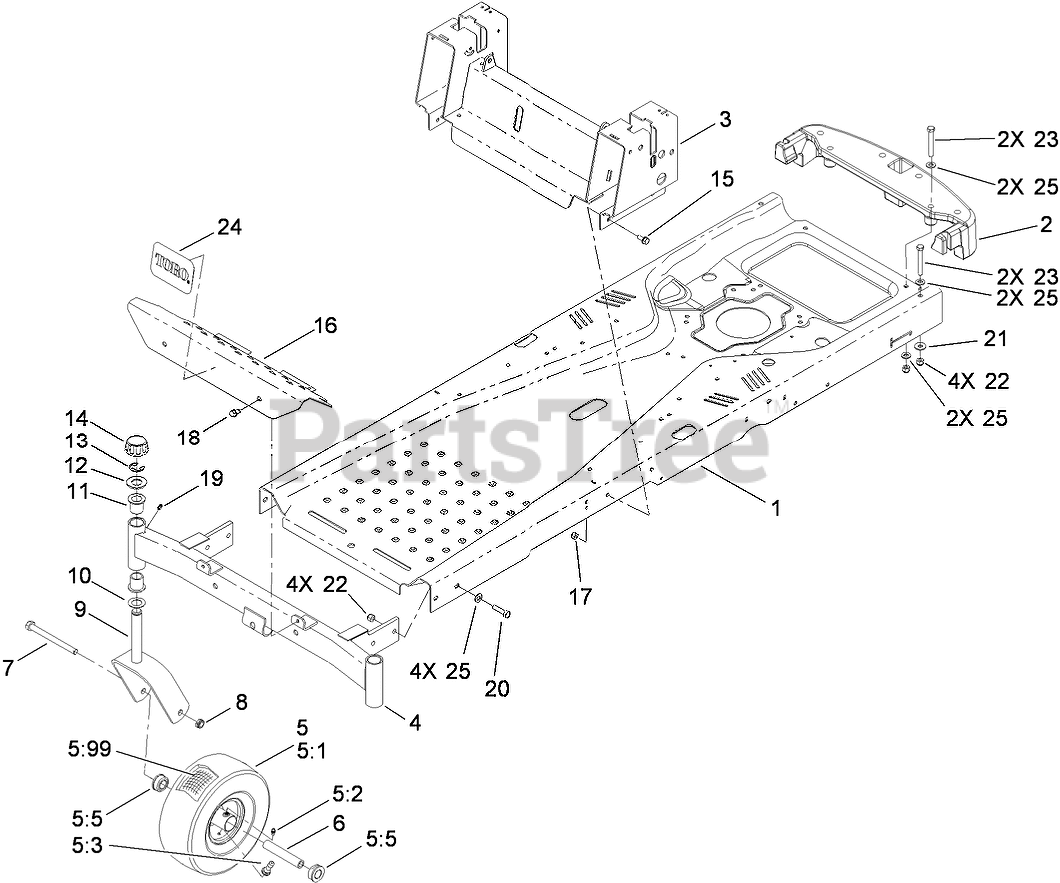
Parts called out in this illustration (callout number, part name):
2	BUMPER-REAR
3	SEAT PIVOT/CONTROL ASM
4	FRONT AXLE ASM
5	CASTER WHEEL ASM (Kenda)
5:1	TIRE-SMOOTH
5:2	FITTING-GREASE
5:3	STEM-VALVE
5:5	BUSHING-FLANGE
5:99	TUBE-INNER (W/VALVE)
6	BUSHING-SPANNER
7	SCREW-HH
8	NUT-LOCK, NI
9	CASTER FORK ASM
10	WASHER-THRUST
11	BEARING-FLANGED
12	WASHER
13	RING-RETAINING, EXT
14	CAP-HUB
15	SCREW-HHF
16	FOOTREST
17	NUT-LOCK, NI
18	SCREW-HWH
19	FITTING-GREASE
20	SCREW-HH
21	WASHER-HARDENED
22	NUT-LOCK, NI
23	SCREW-HH
24	DECAL
25	WASHER-FLAT
